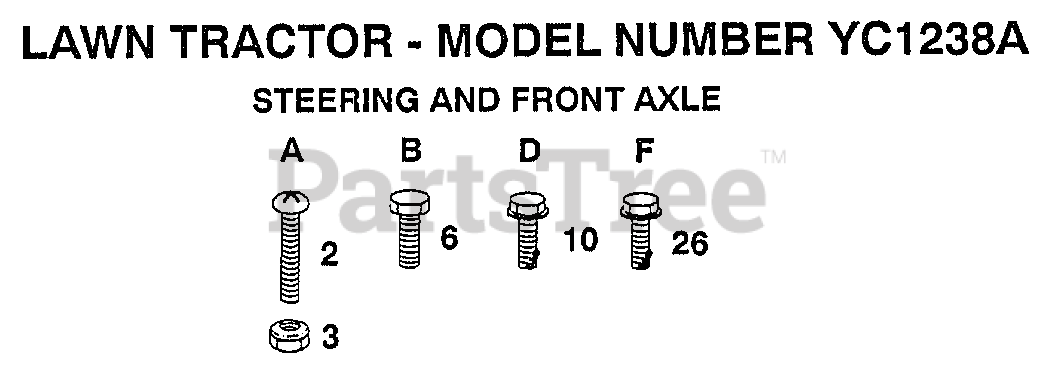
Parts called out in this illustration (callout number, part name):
2	SCREW
6	SCREW LT
10	SCREW LT
26	SCREW
